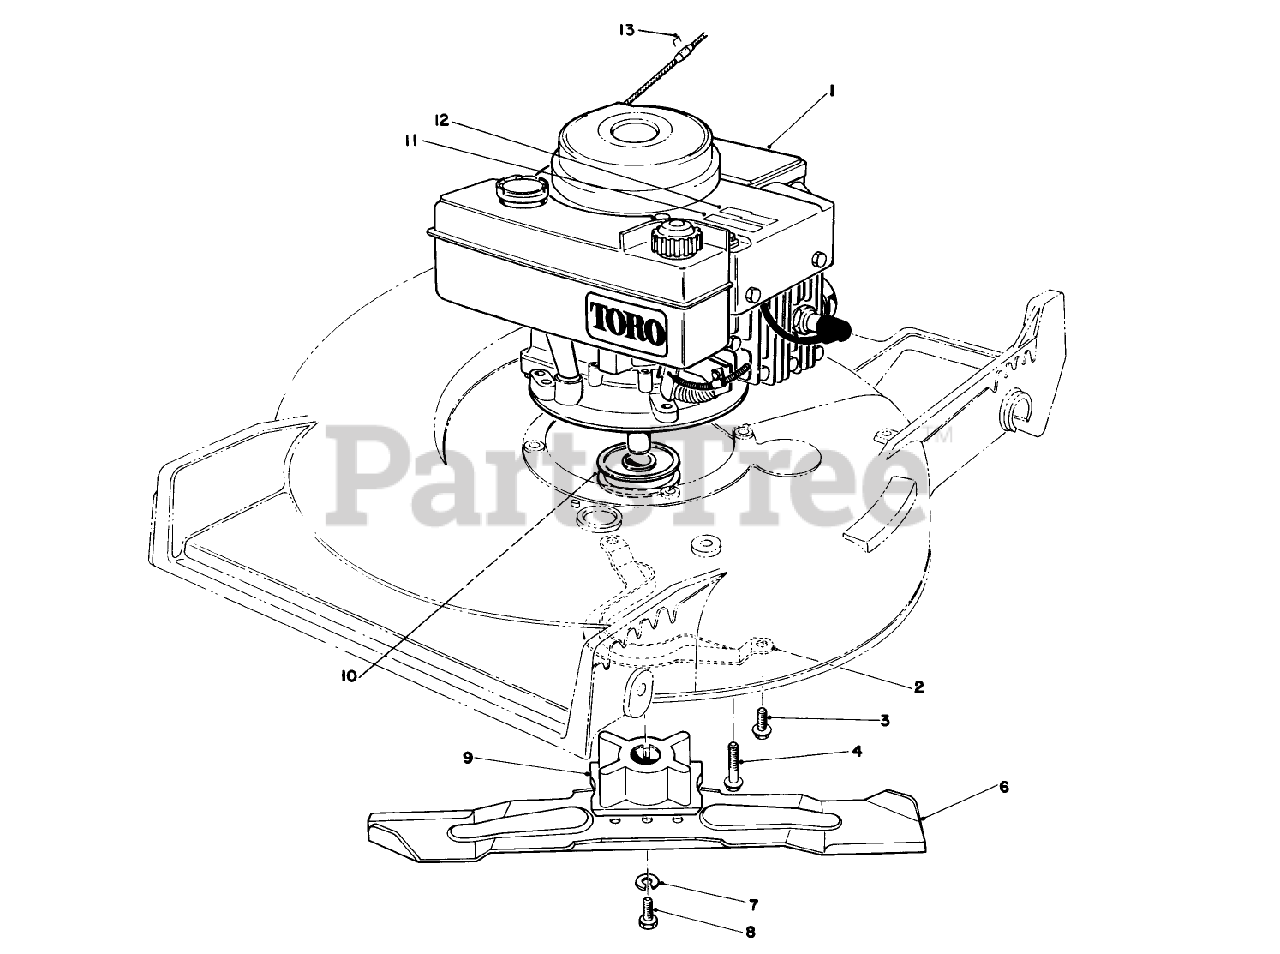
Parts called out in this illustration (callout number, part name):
2	BELT GUIDE
3	SCREW-HWHTF
4	3/8-16 X 2 CAPSCREW
6	BLADE-21in
7	WASHER-LOCK
8	SCREW-BLADE
9	BLADE RETAINER
10	PULLEY-DRIVE, ZONE START
11	Decal-Features
12	ENGINE DECAL
13	Staple
